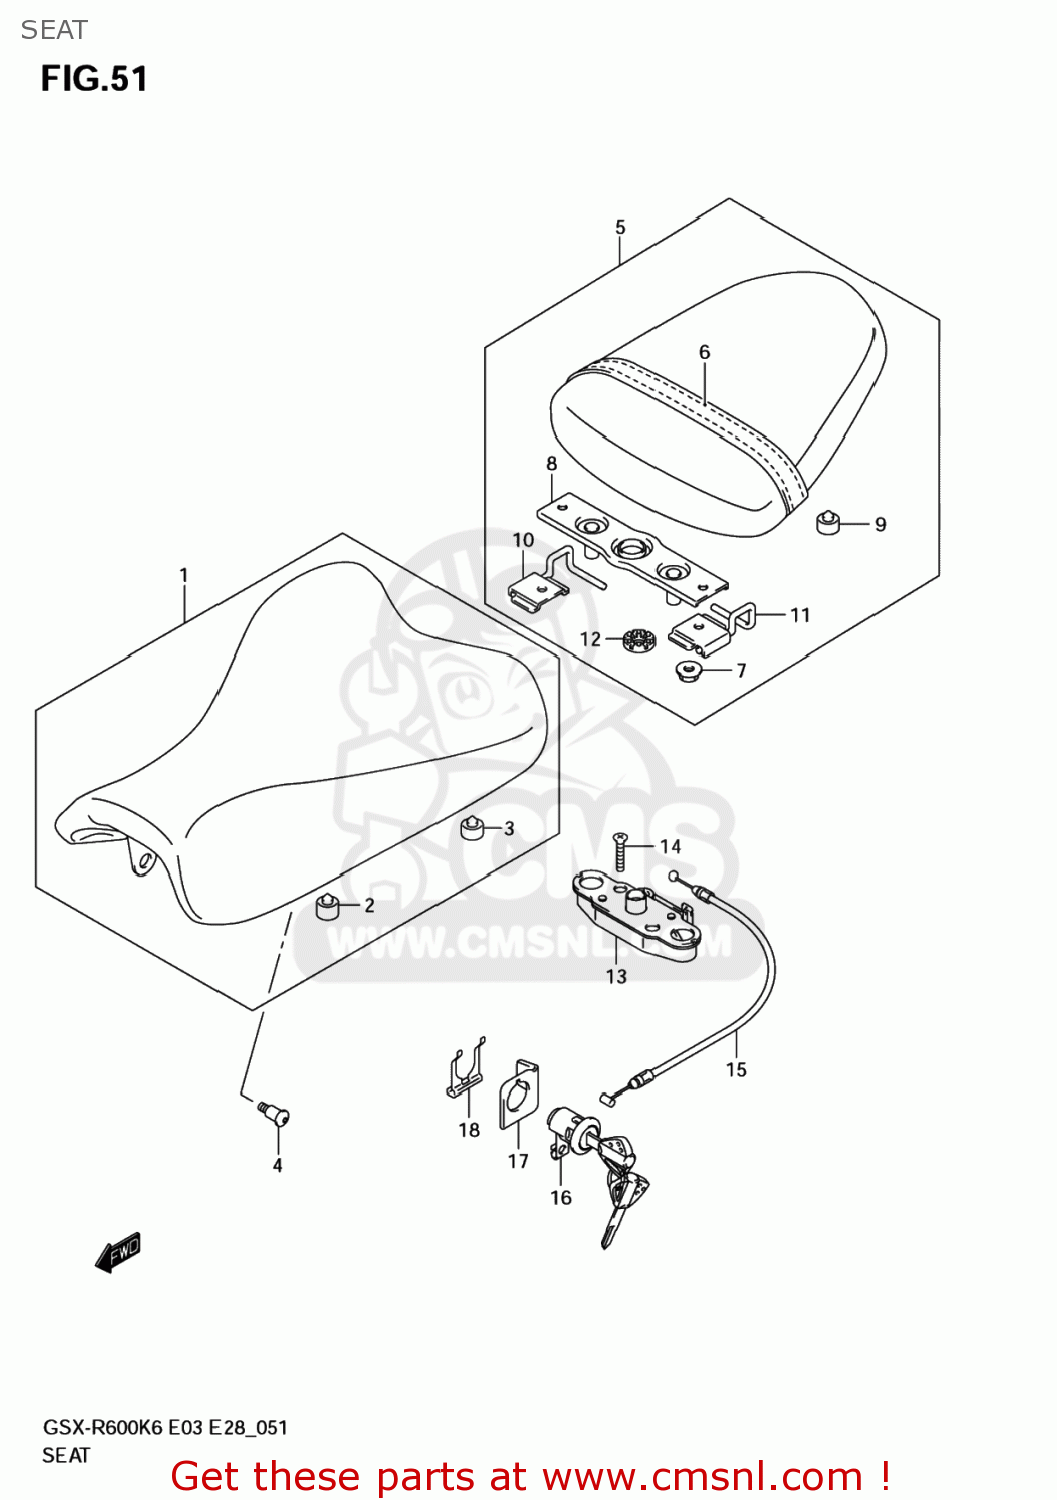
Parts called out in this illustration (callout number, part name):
1	SEAT ASSY
2	CUSHION
3	CUSHION
4	SCREW(6X16)
5	SEAT ASSY,PILLION
6	BAND ASSY
7	NUT
8	STRIKER
9	CUSHION
10	HOLDER,HELMET,R
11	HOLDER,HELMET,L
12	CUSHION
13	BRACKET,SEAT SUPPORT,RIGHT
14	SCREW
15	CABLE,SEAT LOCK
16	LOCK SET,SEAT
17	GUIDE,SEAT LOCK CABLE
18	PLATE,SEAT LOCK ASSY
